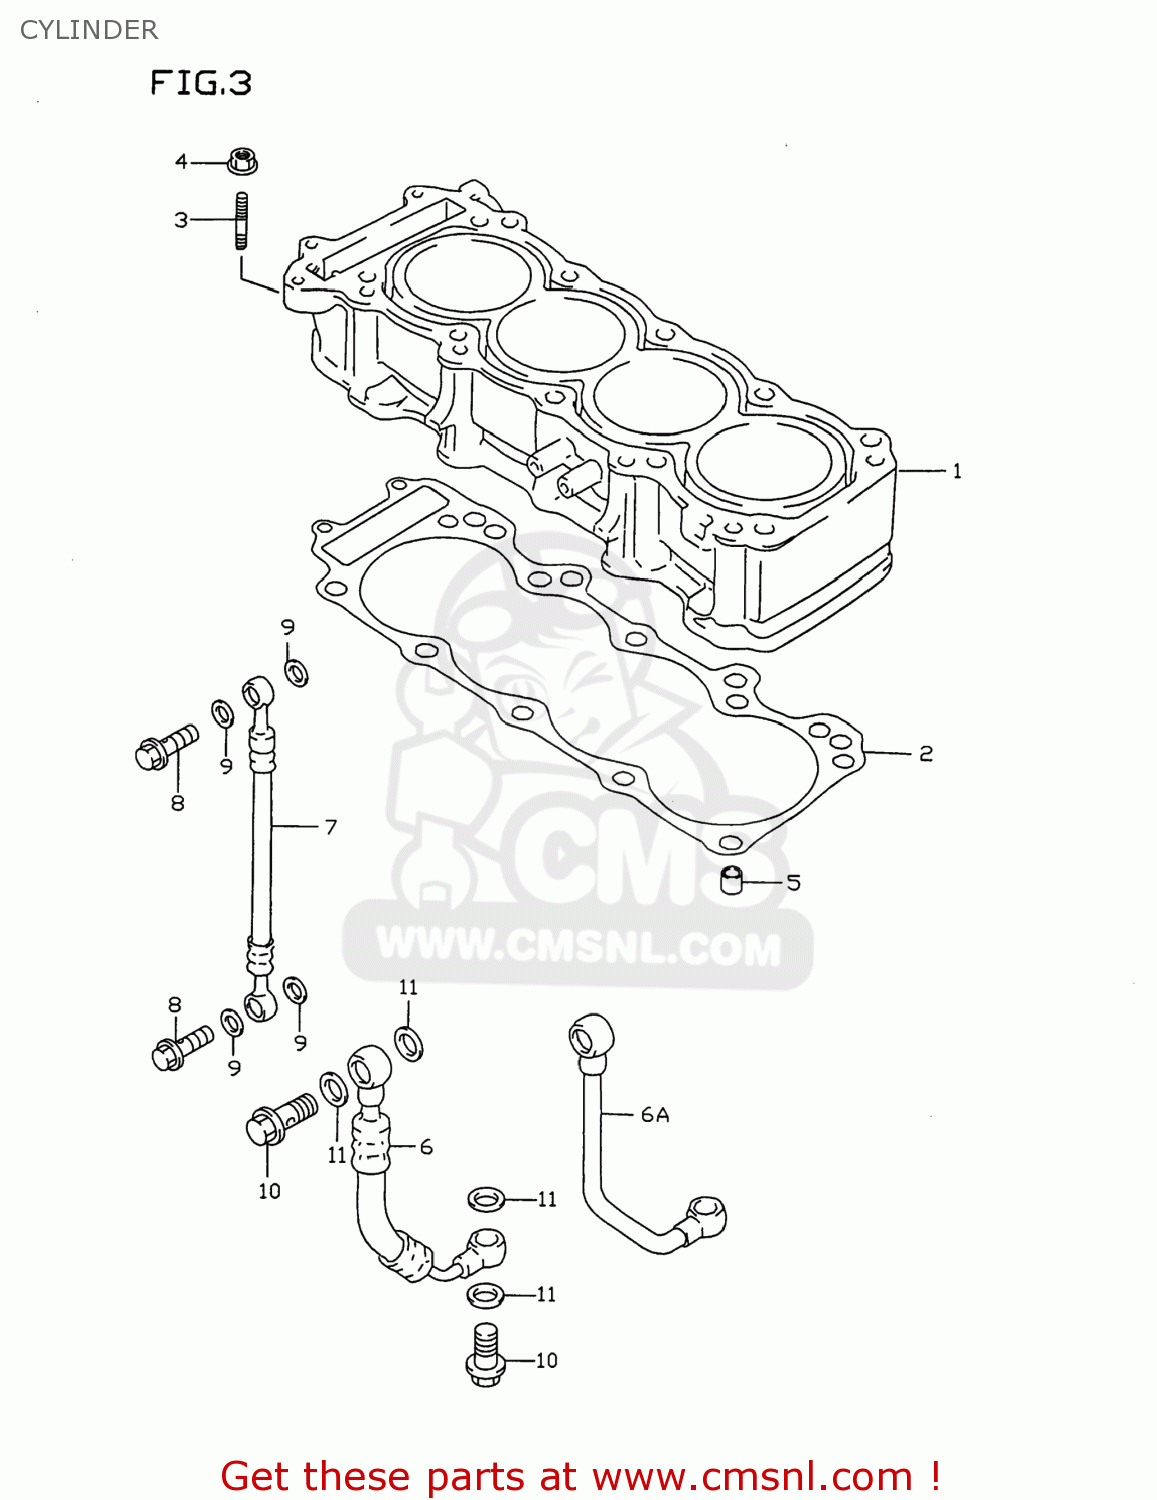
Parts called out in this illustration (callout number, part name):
1	CYLINDER
2	GASKET,CYLINDER(T:0.25)
3	STUD,M6X1X32
4	NUT
5	PIN
6	HOSE,OIL GALLERY
6A	PIPE COMP,CRANKCASE OIL
7	HOSE,CYLINDER HEAD OIL
8	BOLT UNION
9	GASKET(10.1X16X1) (NAS)
10	BOLT UNION
11	GASKET(14X20X1.5) (NAS)
